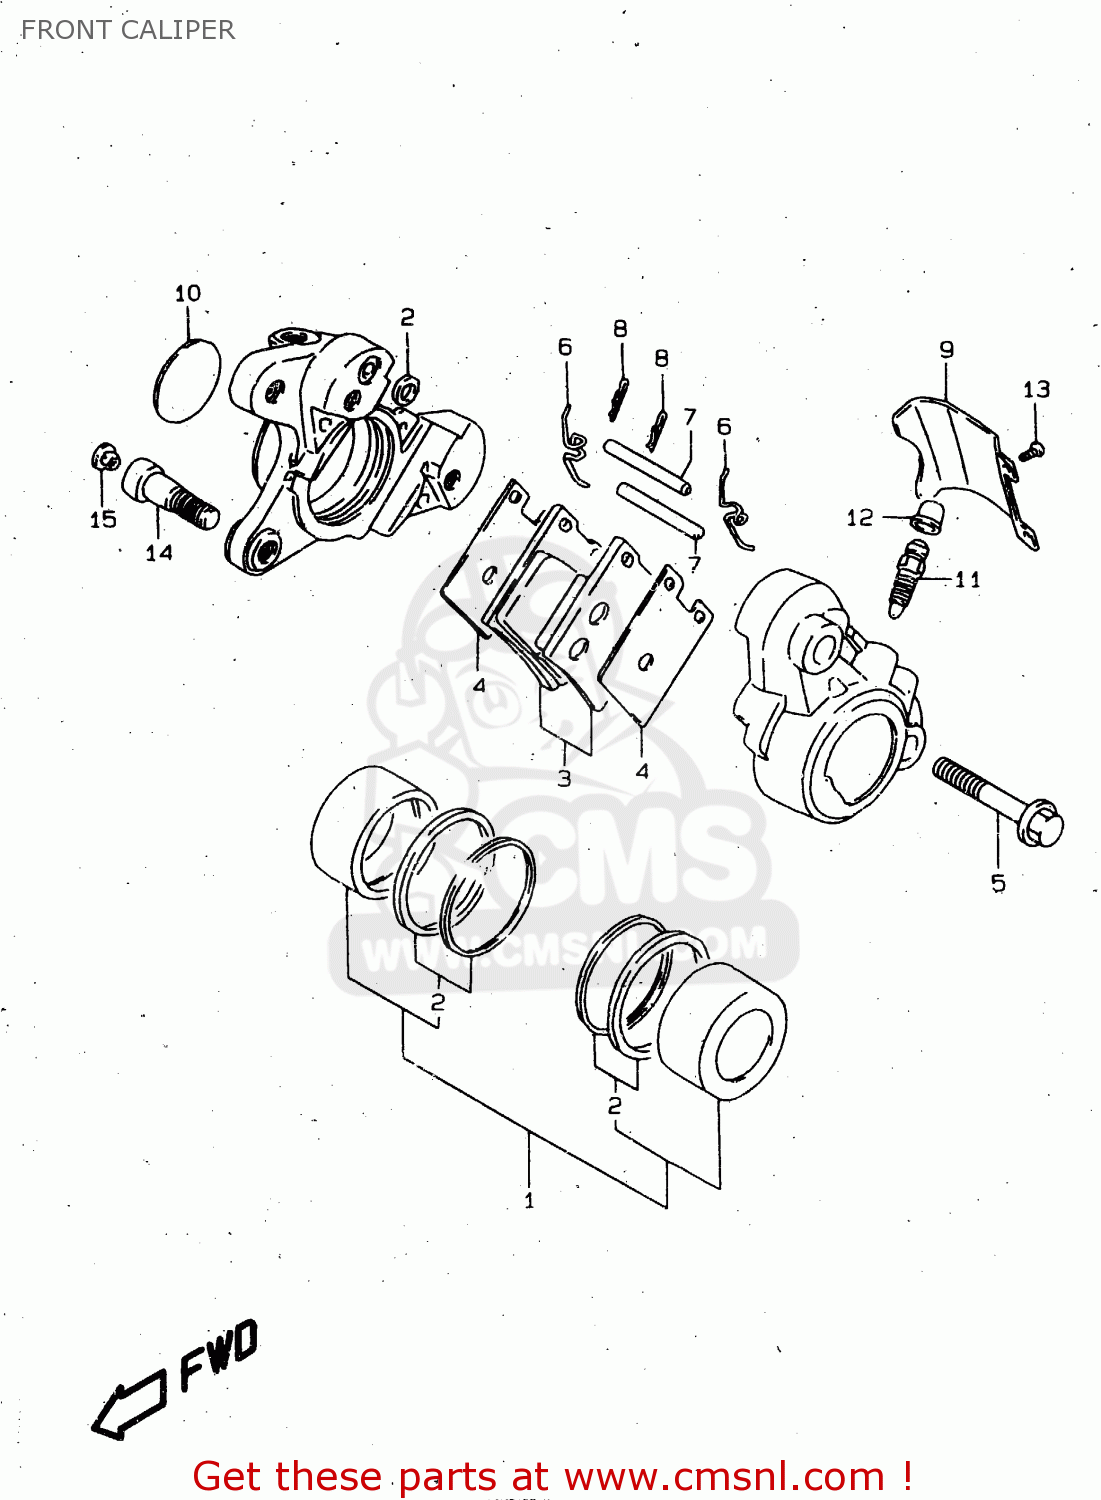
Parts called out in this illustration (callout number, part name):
1	PISTON SET
2	SEAL SET,PISTON
3	PAD SET (NAS)
4	SHIM,PAD
5	BOLT,HOUSING
6	SPRING
7	PIN,PAD
8	CLIP,PAD PIN
9	COVER,CALIPER HOUSING,DUST
10	CAP,CALIPER
11	BLEEDER
12	CAP,BLEEDER PLUG
13	SCREW,CALIPER COVER(4X6)
14	BOLT(10X33)
15	CAP(OD:12)
